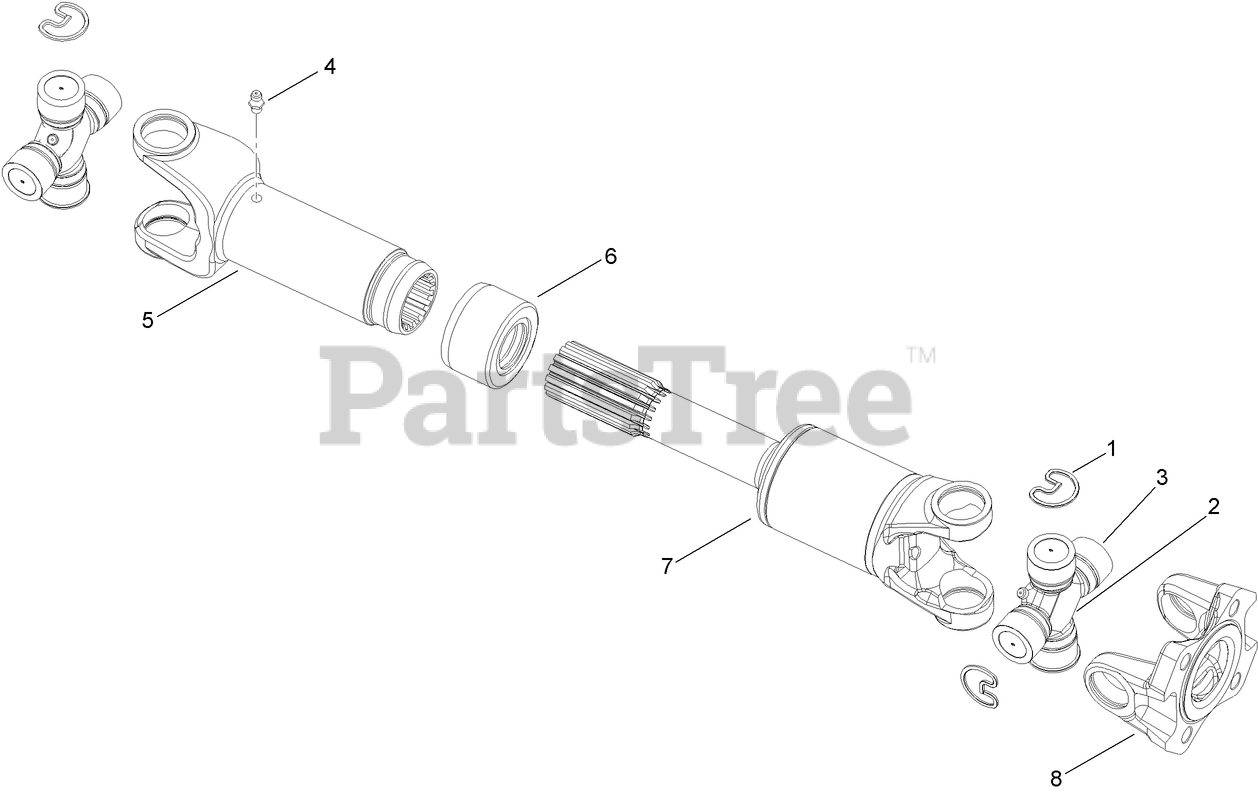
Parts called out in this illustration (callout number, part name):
1	RING-RETAINING
2	JOURNAL
3	Cup-Bearing
4	FITTING-LUBE
7	Shaft
